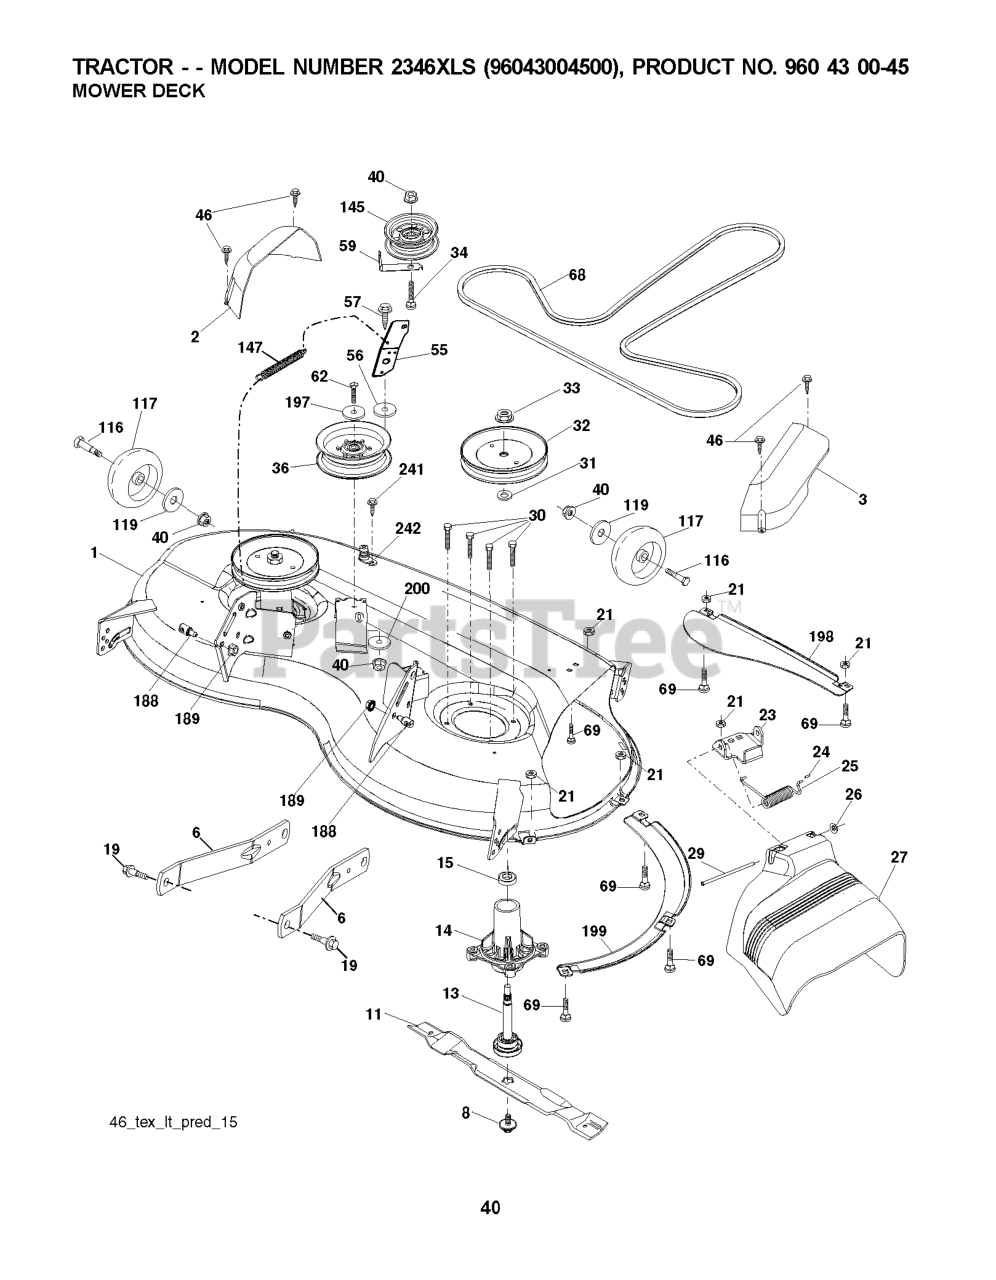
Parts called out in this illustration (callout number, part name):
1	DECK.WLDMT.W/TUBES.46"4GWB.422
2	COVER.MANDREL.RH.46"
3	COVER.MANDREL.LH.46"
6	ARM.SUSPENSION.MOWER.R
8	BOLT.WASHER.ASM.7/16-2
11	BLADE.MOWER.46".HI.LIFT
13	SHAFT.ASM.MDRL.N/GREASE.38
14	RP.HOUSING.MANDREL.4PT.
19	BOLT.SHOULDER
21	LOCKNUT
23	BRKT.DEFLECTOR.38"2005+
24	CAP-SLEEVE LT
25	SPRING.TORSION.DEFLECT
26	NUT PUSH M
27	SHIELD.DEFLECTOR.MOWER.46"BLAC
29	ROD.HINGE
30	SCREW, WASHER HEAD
31	WASHER.SPACER.MANDREL
32	PULLEY.MANDREL.5.438.PD
33	NUT.FLANGE.LOCK.TOP
34	BOLT.3/8-16X1.50
36	PULLEY.IDLER.2006
40	NUT LOCK FLG 3/8-16 UNC
46	SCREW.1/4-20X5/8
56	SPACER.RETAINER
57	SCREW 3/8-16X1
59	GUARD, BELT
62	BOLT-HEX EAK
68	V-BELT
69	BOLT
116	BOLT.SHOULDER.3/8-16X3-5/8.
117	RP WHEEL. GUAGE RALLY
119	WASHER
145	PULLEY.IDLER.48"PRIMARY
147	SPRING.MOWER.DRIVE.ELECTRIC
188	STUD.FASTNER.W/ANTI-ROTATE
189	NUT LOCK HEX FLANGE 5/16-18
197	WASHER
198	BAFFLE CENTER FRONT
199	BAFFLE FRONT RH
200	Washer 13/32 x 2 x 10 Ga.
241	SCREW.TT.#10-32X.5.3/8.FLANGE
242	PORT.WASHOUT
